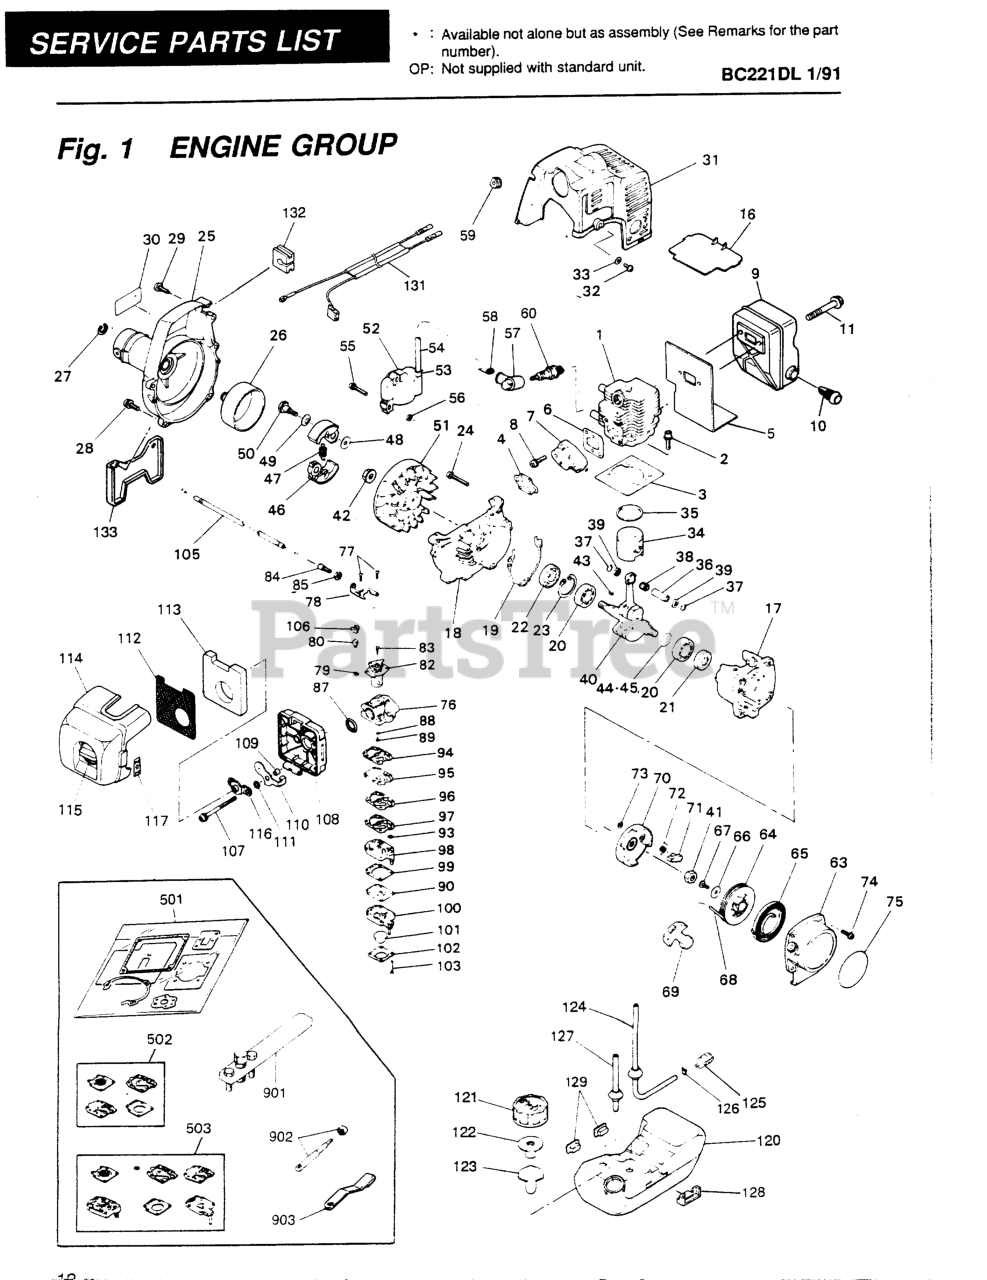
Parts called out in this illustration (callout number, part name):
1	CYLINDER
2	BOLT, M5 X 22
8	SCREW, M5 X 20
10	ARRESTER (RPLS 5850-15140)
11	BOLT(NO LONGER AVAILABLE)
17	CRANKCASE (RPLS -21100)
18	CRANKCASE (RPLS -21100)
20	BEARING
22	SEAL, OIL (RPLS 1140-21220)
23	RING, SNAP, M28 x 1.2
24	SCREW, M5 x 30(RPLS 0263-00530
25	HOUSING ASSEMBLY
26	HOUSING ASSEMBLY
27	RING, SNAP
28	SCREW, M5X20 (RPLS.1400-75510)
29	SCREW, HOUSING
32	SCREW, M4 x 12
33	WASHER
34	PISTON
35	RING, PISTON (RPLS 1850-41210)
36	PIN, PISTON 5x8x26
37	RING, SNAP (RPLS 1101-41320)
39	WASHER
43	KEY
45	SHIM (NO LONGER AVAILABLE)
48	WASHER, FLAT (USE 182303)
49	WASHER (RPLS -51241)
50	BOLT
52	COIL
53	CORD
54	CAP
55	SCREW, M4 X 22
58	SPRING
59	GROMMET
63	RECOIL
64	REEL
65	SPRING, SPIRAL
66	WASHER (NO LONGER AVAIL)
72	SPRING, RETURN
73	E-RING
74	SCREW, M4 X 16
75	LABEL
77	SCREW
79	RING
80	SWIVEL
82	VALVE ASSEMBLY
85	NUT, CABLE ADJUSTER
87	RING, PACKING
88	RING, O
90	DIAPHRAGM (USE 4810-81260)
94	GASKET, PUMP
95	DIAPHRAGM
96	PLATE, PUMP (NLA)
97	GASKET, PLATE
98	KIT ONLY
99	KIT ONLY
100	BODY
101	PUMP, PRIMING
102	COVER
103	SCREW
105	CABLE COMP (RPLS 1633-83100)
106	CAP, CABLE END
108	BODY (RPLS -82110)
109	SLEEVE
113	ELEMENT
117	LABEL
121	CAP (USE 5601-85201)
122	VALVE (NO LONGER AVAILABLE)
124	PIPE COMP (NO LONGER AVAIL)
125	5500-85400 (RRLS. 1750-85300)
126	CLIP (REPLACES 2841-31280)
128	CUSHION (S)
129	CUSHION (F)
501	KIT, GASKET
502	DIA/GASK KIT, 220,260,230
503	KIT, REBUILD, BT/BC220
902	(H) ROD ASSY
